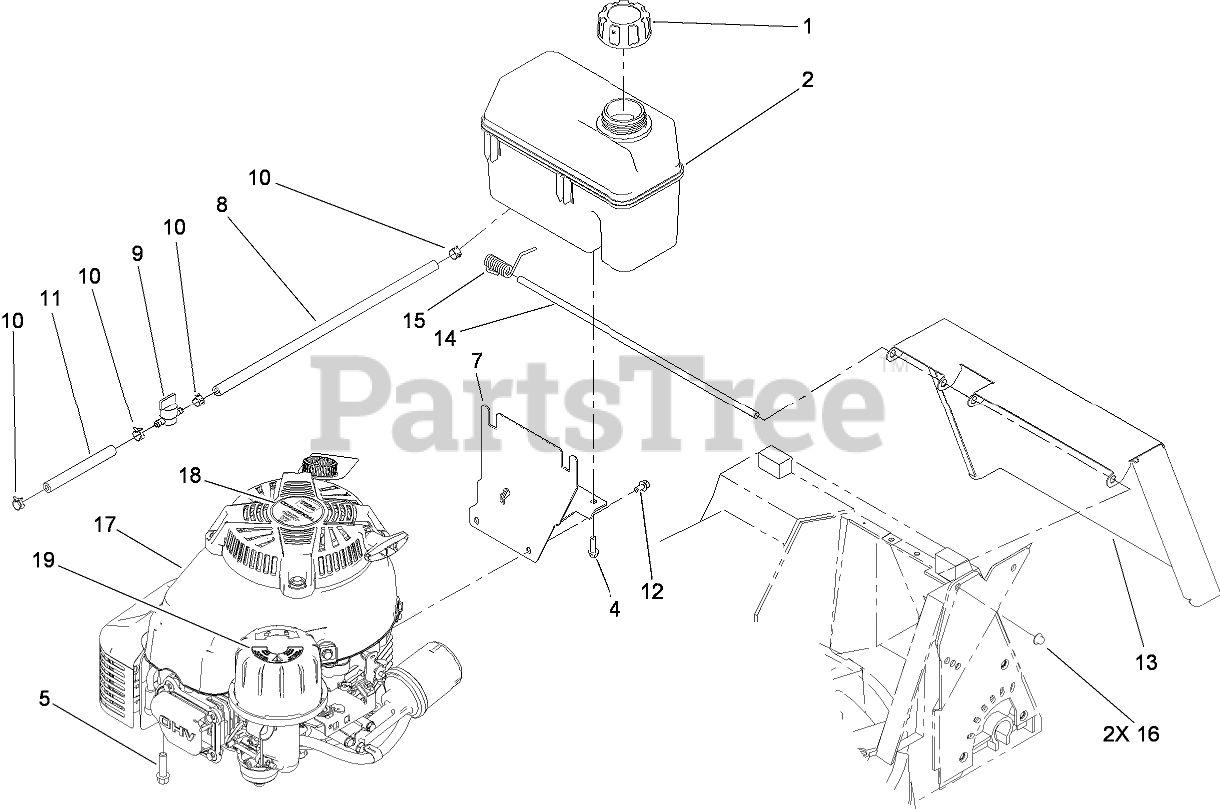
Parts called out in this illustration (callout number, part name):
1	CAP-GAS
2	Tank-Fuel
4	SCREW-HWH
5	SCREW-TAPTITE
7	MOUNT-TANK
8	HOSE-FUEL
9	VALVE-FUEL
10	CLAMP-HOSE
11	HOSE-FUEL
12	SCREW-HWH
13	DOOR-DISCHARGE, REAR
14	ROD-DOOR
15	SPRING-TORSION, DOOR
16	PUSHNUT-CAP, WASHER
17	ENGINE-KAWASAKI, FJ180V-AS30
18	DECAL
